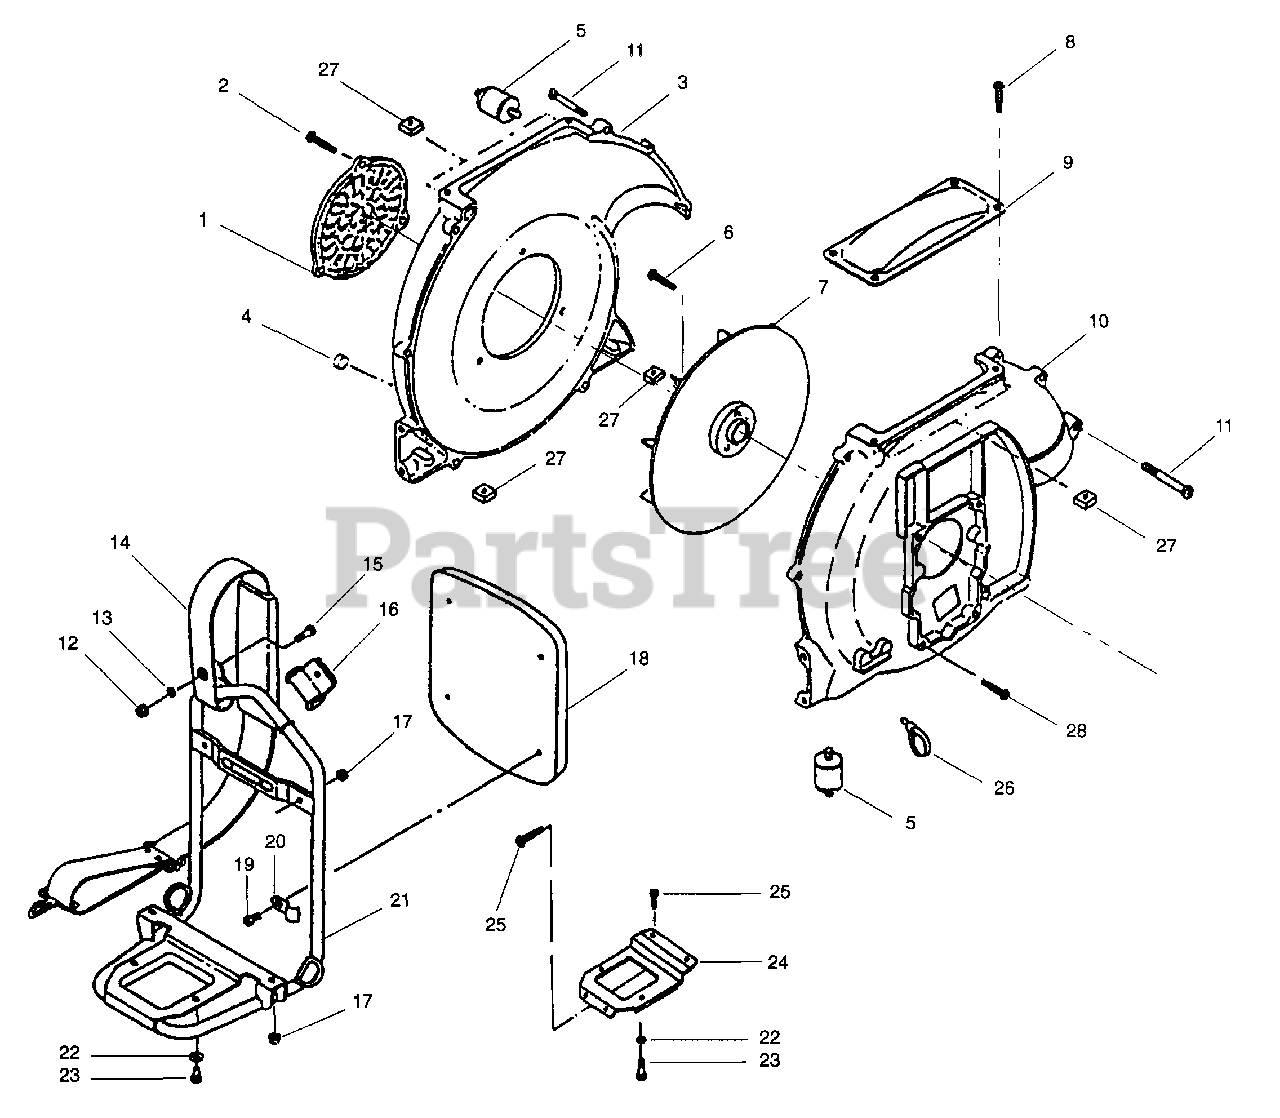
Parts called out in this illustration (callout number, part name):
1	Fan Cover - Type 1
2	Screw - Type 1
3	Front Fan Case
4	Cap-Type 1
5	Isolator
9	Cover
10	Rear Fan Case
14	Shoulder Band
21	Frame
24	Bracket - Type 1
25	Bolt - Type 1
26	Wire Band
